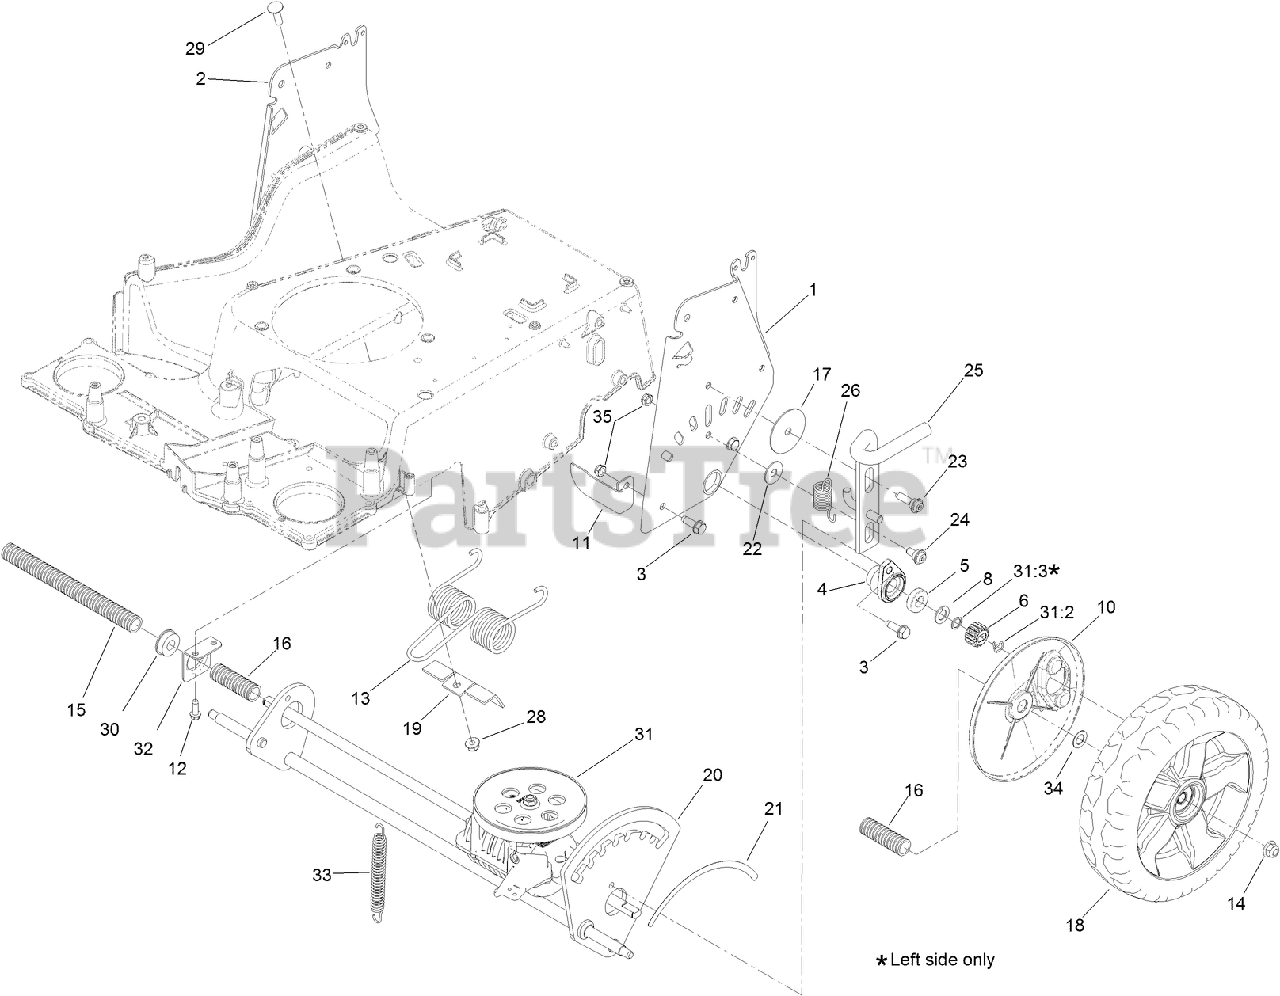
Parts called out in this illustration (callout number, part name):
1	LH HOC PLATE ASM
2	RH HOC PLATE ASM
3	SCREW-HWHTF
4	RETAINER-BEARING
5	BEARING-BALL
6	GEAR-PINION, 15T
8	WASHER-THRUST
10	COVER-GEAR
11	BRACKET-STOP
12	SCREW-HWHTF
13	SPRING-TORSION
14	NUT-HF, NI
15	CONDUIT-CONVOLUTED
16	CONDUIT-CONVOLUTED
17	WASHER-PLAIN
18	WHEEL ASM (W/GEAR)
19	BRACKET
20	AXLE-REAR
21	DECAL-HOC, REAR
22	WASHER
23	SCREW-SHOULDER, BHTF
24	BOLT-SHOULDER
25	LOCK-HEIGHT, ADJUST
26	SPRING-EXTENSION
28	NUT-HF, NI
29	BOLT-CARR
30	BEARING-BALL
31	TRANSMISSION KIT
31:2	PIN-SNAP
31:3	RING-RETAINING
32	MOUNT-BEARING
33	SPRING-EXTENSION
34	WASHER-PLAIN
35	NUT-LOCK, NI
